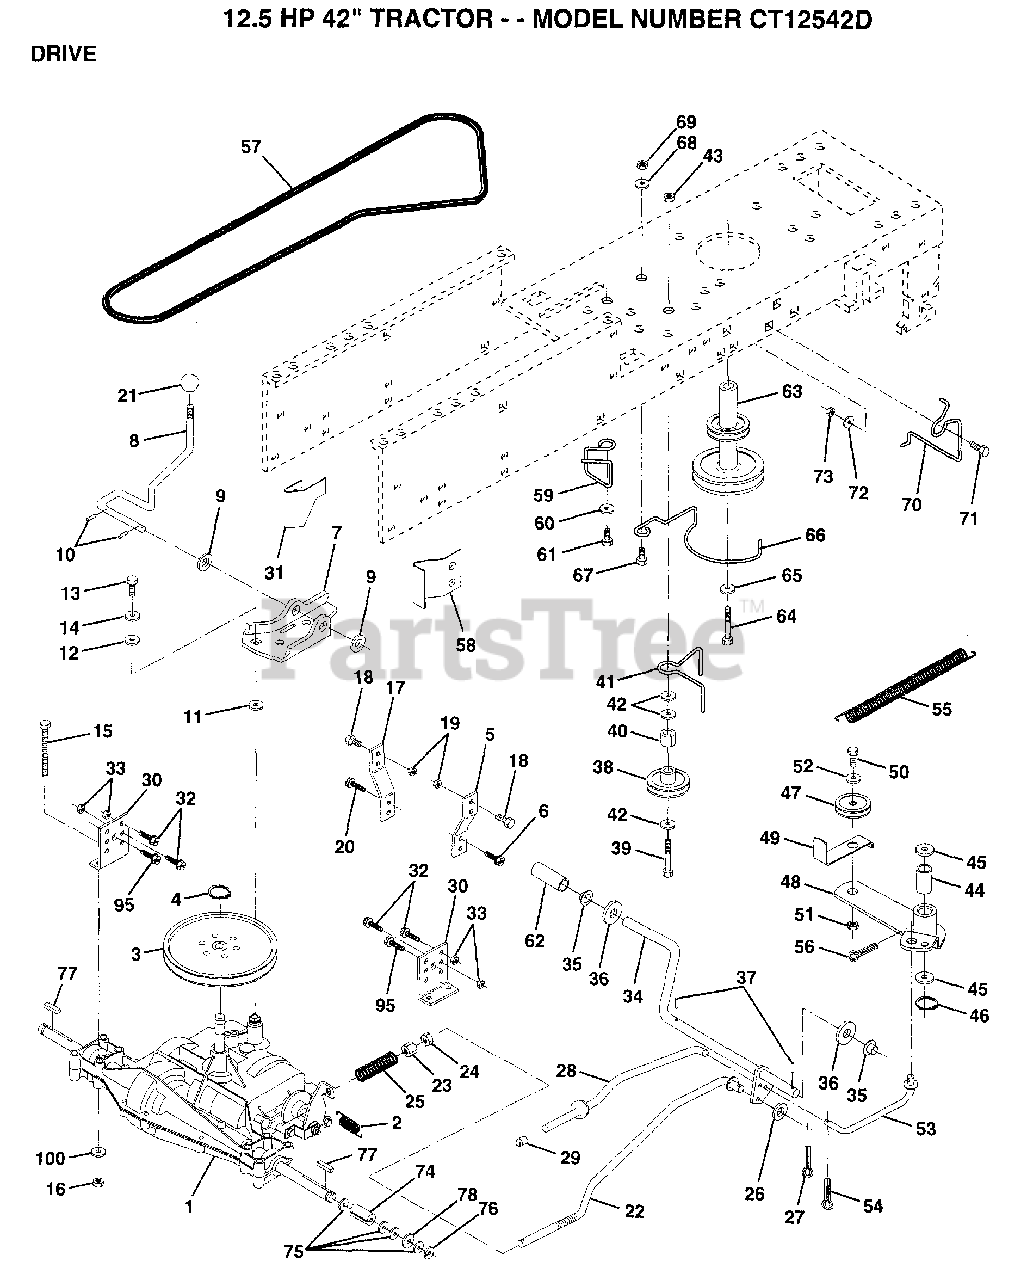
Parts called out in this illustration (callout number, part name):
3	PULLEY TRANS
5	STRAP TORQUE
6	SCREW
8	SHIFT ROD
9	WASHER
10	PIN COTTER 1/8
11	WASH-SHFT PLT LT
12	WASHER LT
14	LOCKWASHER
15	BOLT HEX
17	STRAP TORQUE
19	NUT
20	SCREW
21	CONTROL KNOB LT
22	BRAKE ROD
23	NUT
24	NUT
25	SPRING ROD LT
26	WASHER
27	COTTER PIN
28	ROD PARK BRAKE
30	TRANSAXLE MTG BKT
31	"KEEPER,BELT LH T"
32	BOLT
33	NUT
35	NYLON BEARING
36	WASHER LT
38	PULLEY.IDLER.FLAT
39	BOLT
40	SPACER T
41	BELT KEEPER LT
42	WASHER
43	NUT
44	"LY, BEARING"
45	WASHER LT
46	KLIP RING
48	ARM IDLER
49	RETAIN BELT
52	WASHER
53	"LINK, CLUTCH T"
54	COTTER PIN
55	"SPRING, RETURN LT"
56	COTTER PIN
58	"KEEPER,BELT RH T"
59	KEEPER BELT CNTSP
60	WASHER
61	SCREW
62	PEDAL COVER T
63	PULLEY.ENGINE
64	BOLT
65	LOCKWASHER
66	KEEPER.BELT.ENG.L
67	BOLT
68	WASHER
70	KEEPER BELT ENG
71	BOLT
72	WASHER
74	SPACER LT
75	WASHER
76	E-RING LT
77	SQUARE KEY
78	WASHER
95	SCREW
100	WASHER M
